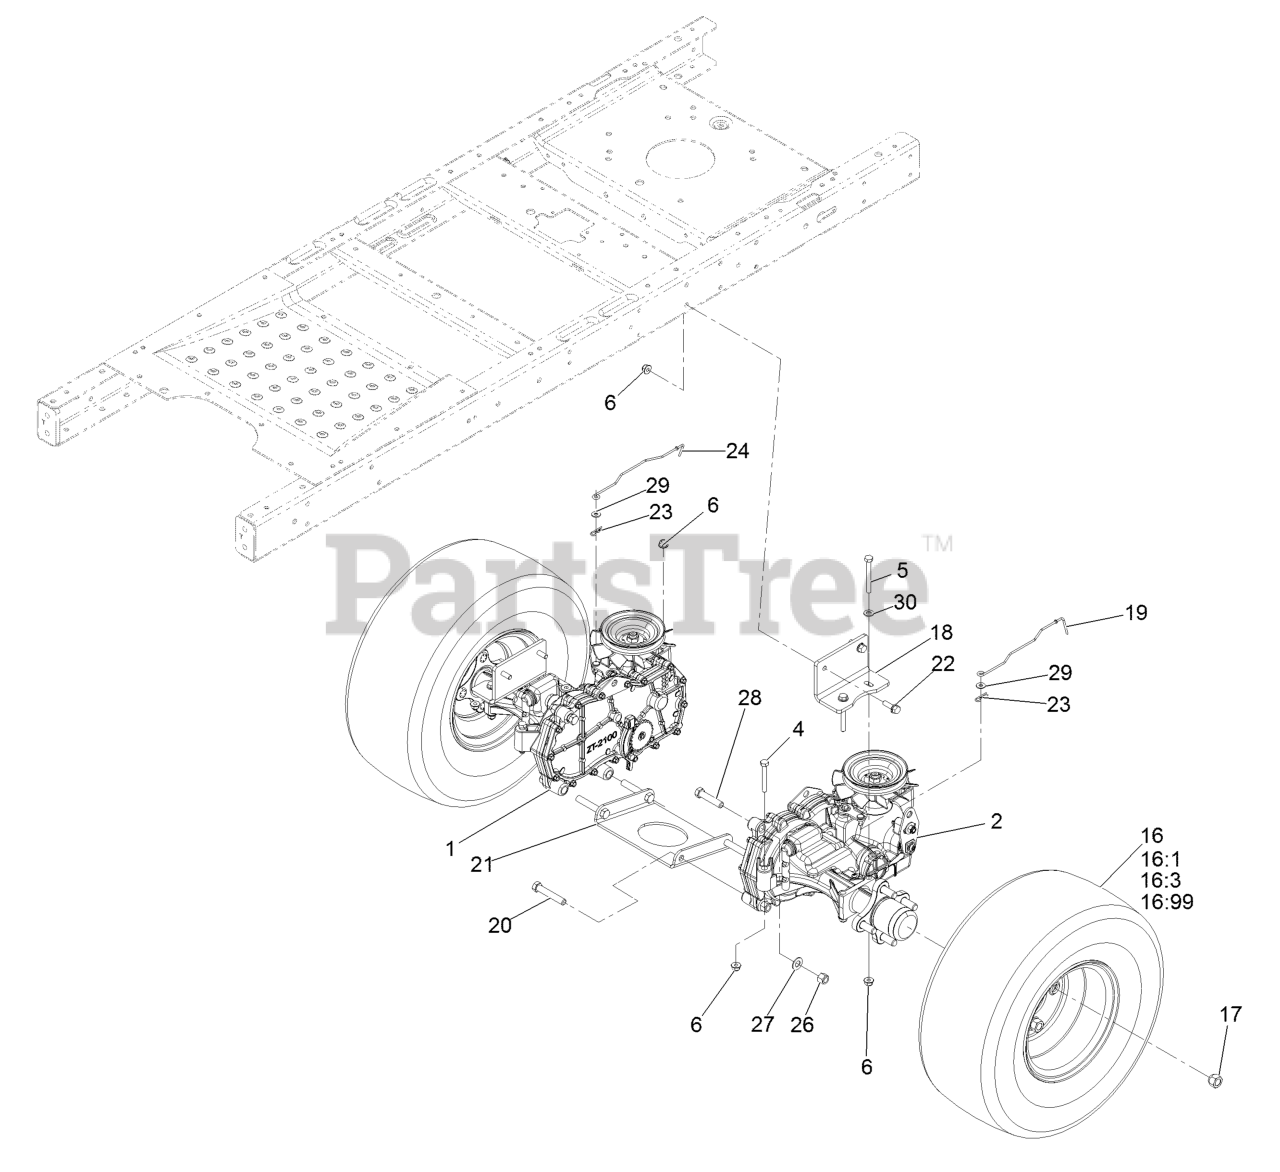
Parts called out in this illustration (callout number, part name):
1	RH HYDRO TRANSAXLE ASM
2	LH HYDRO TRANSAXLE ASM
4	SCREW-HH
5	SCREW-HH
6	NUT-HF, NI
16	2 PLY WHEEL AND TIRE ASM
16:1	TIRE-2 PLY
16:3	Stem-Valve
16:99	TUBE-TIRE
17	NUT-LUG
18	MOUNT-HYDRO
19	ROD-BYPASS, LH
20	SCREW-HH
21	PLATE-CROSS, HYDRO
22	SCREW-HHF
24	ROD-BYPASS, RH
26	NUT-LOCK, NI
27	WASHER-FLAT
28	SCREW-HH
30	WASHER-PLAIN
